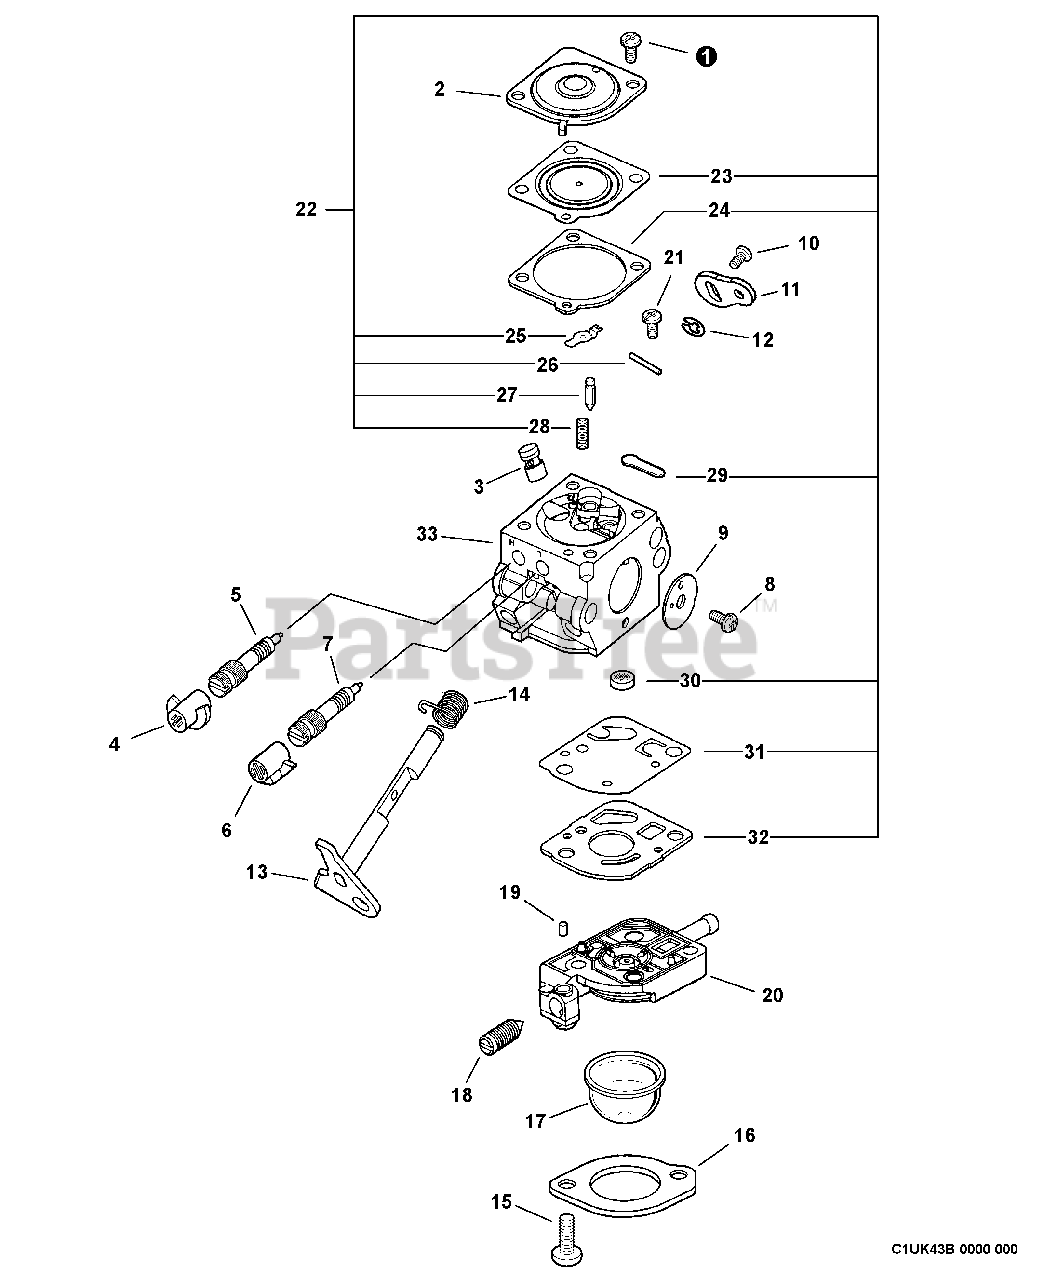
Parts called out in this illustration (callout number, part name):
2	COVER, DIAPHRAGM
3	NOZZLE, CHECK VALVE
4	CAP, LIMITER
5	NEEDLE, HIGH SPEED
6	CAP, LIMITER - WHITE
7	NEEDLE, LOW SPEED
8	SCREW 3×4.5
9	VALVE, THROTTLE
11	LEVER, THROTTLE
13	SHAFT, THROTTLE
14	SPRING, THROTTLE RETURN
16	RETAINER
17	BULB, PURGE
19	PIECE, FRICTION
20	BODY ASSY, PURGE
22	REBUILD KIT
23	DIAPHRAGM
24	GASKET, DIAPHRAGM
25	LEVER, METERING
26	PIN, METERING LEVER
27	VALVE, INLET NEEDLE
28	SPRING, METERING LEVER
29	PLUG, WELCH
30	STRAINER
31	DIAPHRAGM, PUMP
32	GASKET, PUMP
33	BODY, CARBURETOR
